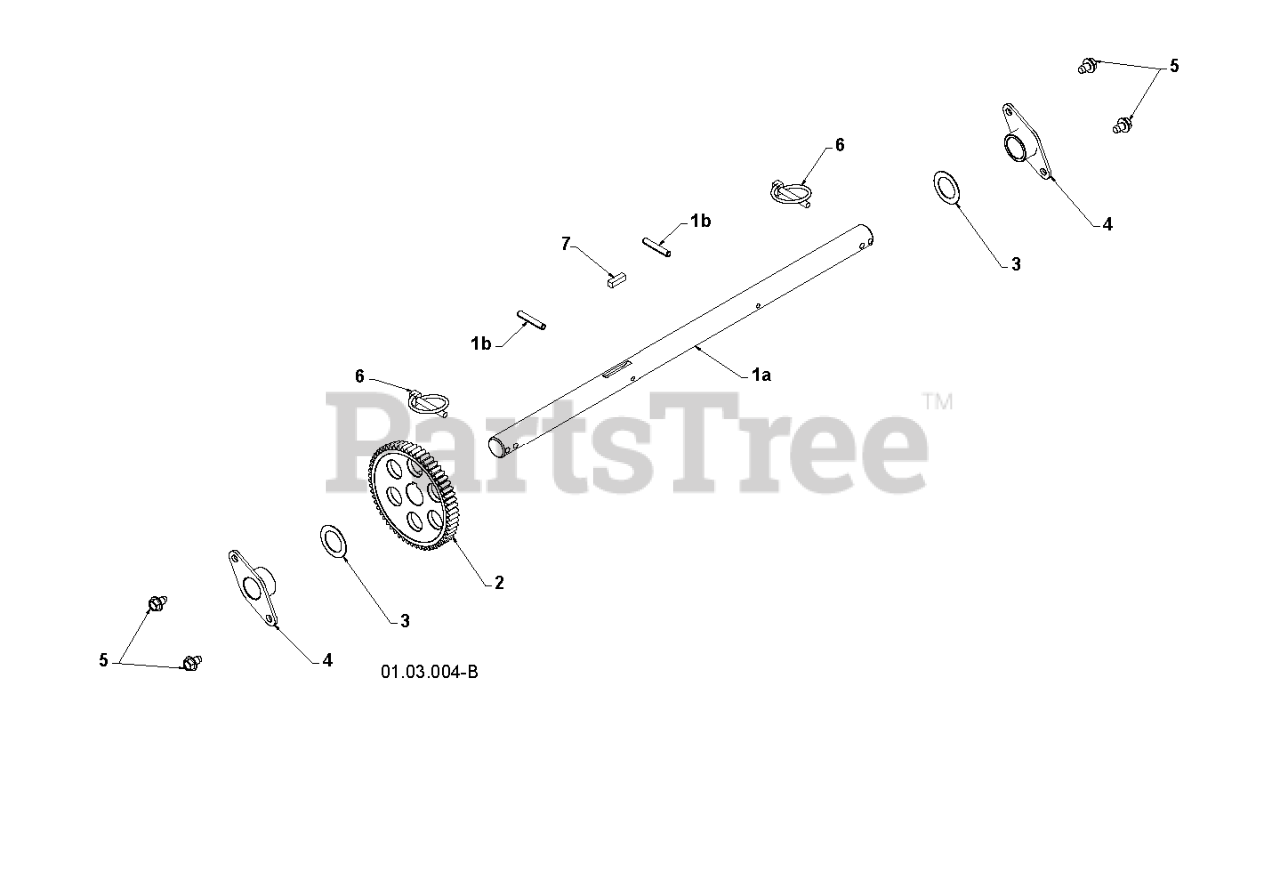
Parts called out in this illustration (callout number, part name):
1	AXLE.SHAFT.ASM.W/ROLPIN.NON-PS
2	GEAR, AXLE (58T)
3	WASHER TRUST 1"
4	BEARING, AXLE
5	Screw 5/16-18 x 1/2 Hex, Self Tapping 5/16-18 x 1/2
6	PIN KLIK, 1/4
7	KEY, SQUARE 1/4 X .875
